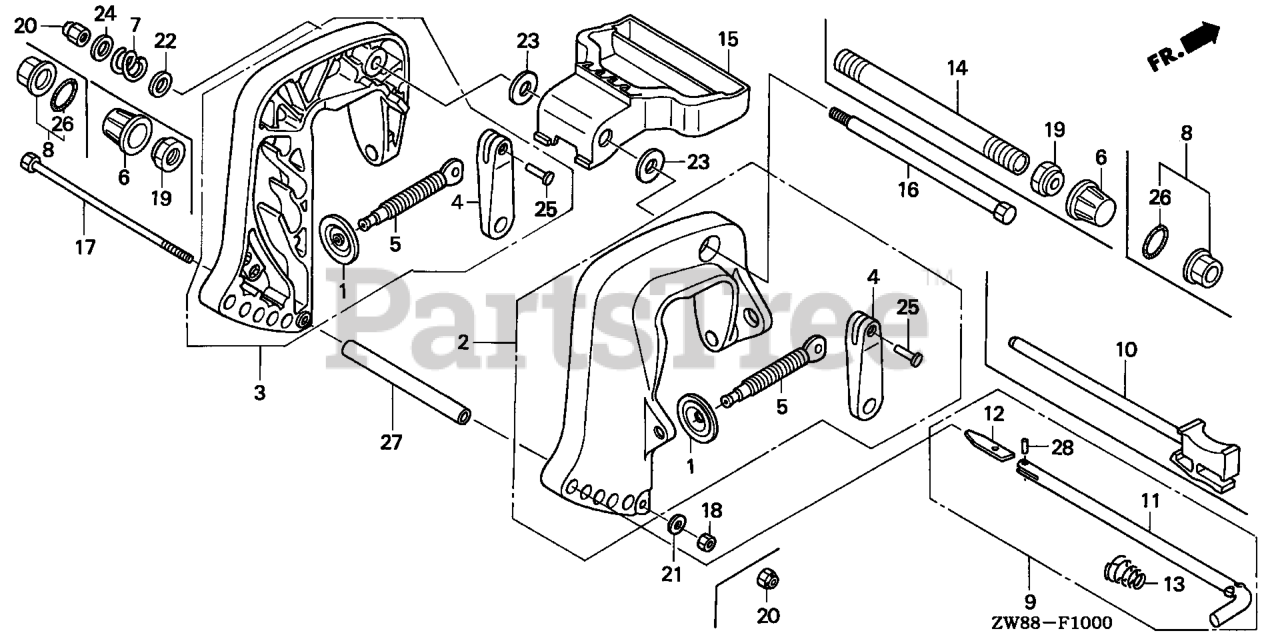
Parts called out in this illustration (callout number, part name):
1	PLATE, PUSH
2	BRACKET, R. STERN *NH282MU* (OYSTER SILVER METALLIC-U)
3	BRACKET, L. STERN *NH282MU* (OYSTER SILVER METALLIC-U)
4	GRIP, CLAMP
5	SCREW, CLAMP
6	CAP, TILTING BOLT
9	ROD, ADJUSTING
11	ROD, ADJUSTING
12	STOPPER, ROD
13	SPRING, ADJUSTING ROD
14	SHAFT, TILTING
15	HANDLE, CARRYING REMOTE
17	BOLT, HEX. (8X163)
19	NUT, SELF-LOCK (7/8-14UNF)
20	NUT, SELF-LOCK (8MM)
21	WASHER, PLAIN (8MM) Use up to Frame SN 4800712.
23	WASHER, WAVE (22MM)
25	RIVET (4X22.6)
27	COLLAR, DISTANCE (8MM)
28	PIN, SPRING (2.5X8)
